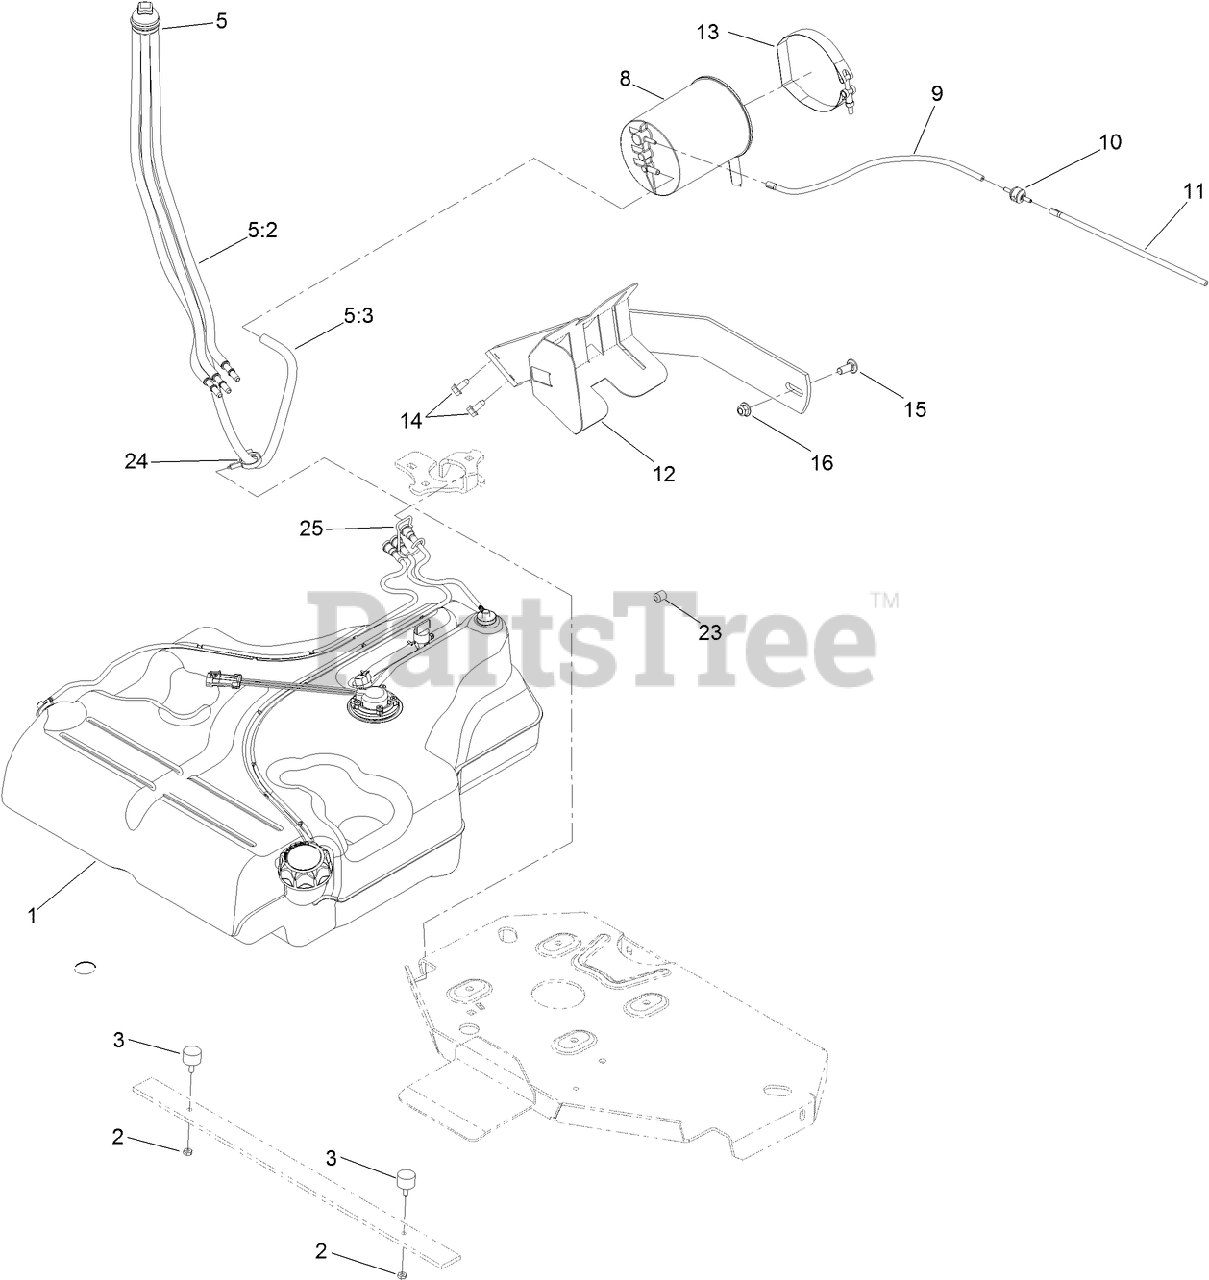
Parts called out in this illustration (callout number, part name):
1	FUEL TANK ASM
2	NUT-JAM
3	BUMPER-RUBBER (W/ STUD)
5	FUEL MANIFOLD VENT ASM
5:2	HOSE-FUEL
5:3	HOSE-FUEL
8	CANISTER-CARBON, 1200CC
9	HOSE-VENT, FORMED
10	VALVE-CHECK, VACUUM
11	HOSE-VENT, FORMED
12	MOUNT-CANISTER
13	CLAMP-T-BOLT
14	SCREW-HWHTF
15	SCREW-CARR
16	NUT-HF, NI
23	PLUG-PORT
24	CLAMP-HOSE
25	RETAINER-LINE, VAPOR
